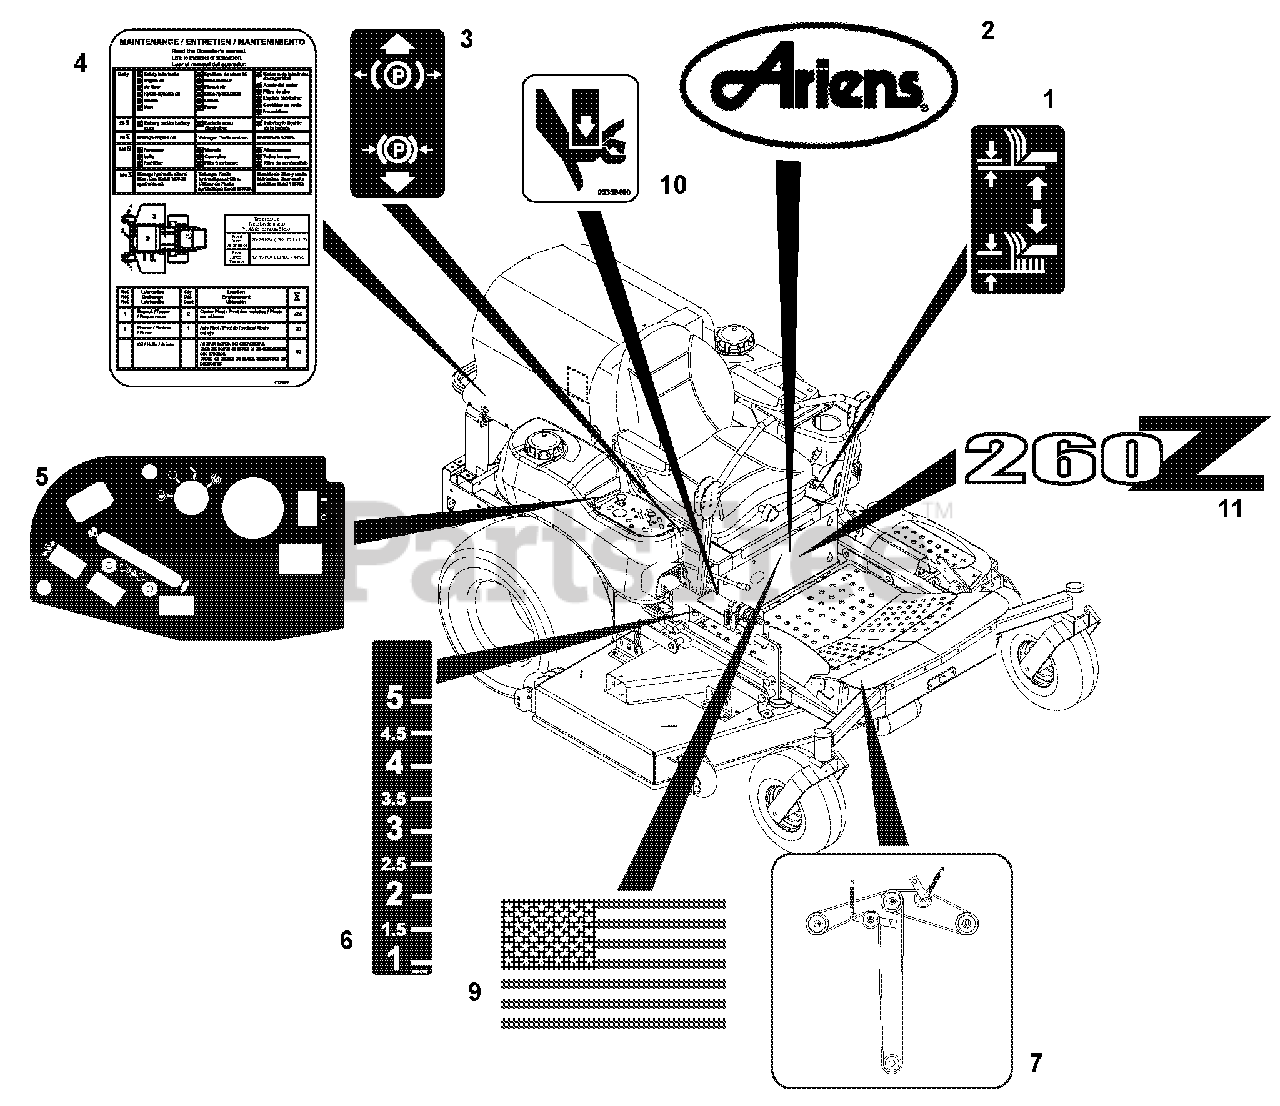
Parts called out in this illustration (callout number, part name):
1	Decal, Lift Lever
2	Decal, Ariens
3	Decal, Parking Brake Lever
4	Decal, Service Instructions
5	Decal, Control Panel
6	Decal, Height of Cut
7	Decal, Belt Diagram (316, 317, 322)
8	Decal, PM-260Z
9	Decal, American Flag
10	Decal, Pinch Point
11	Decal, PM260Z (316, 317)
